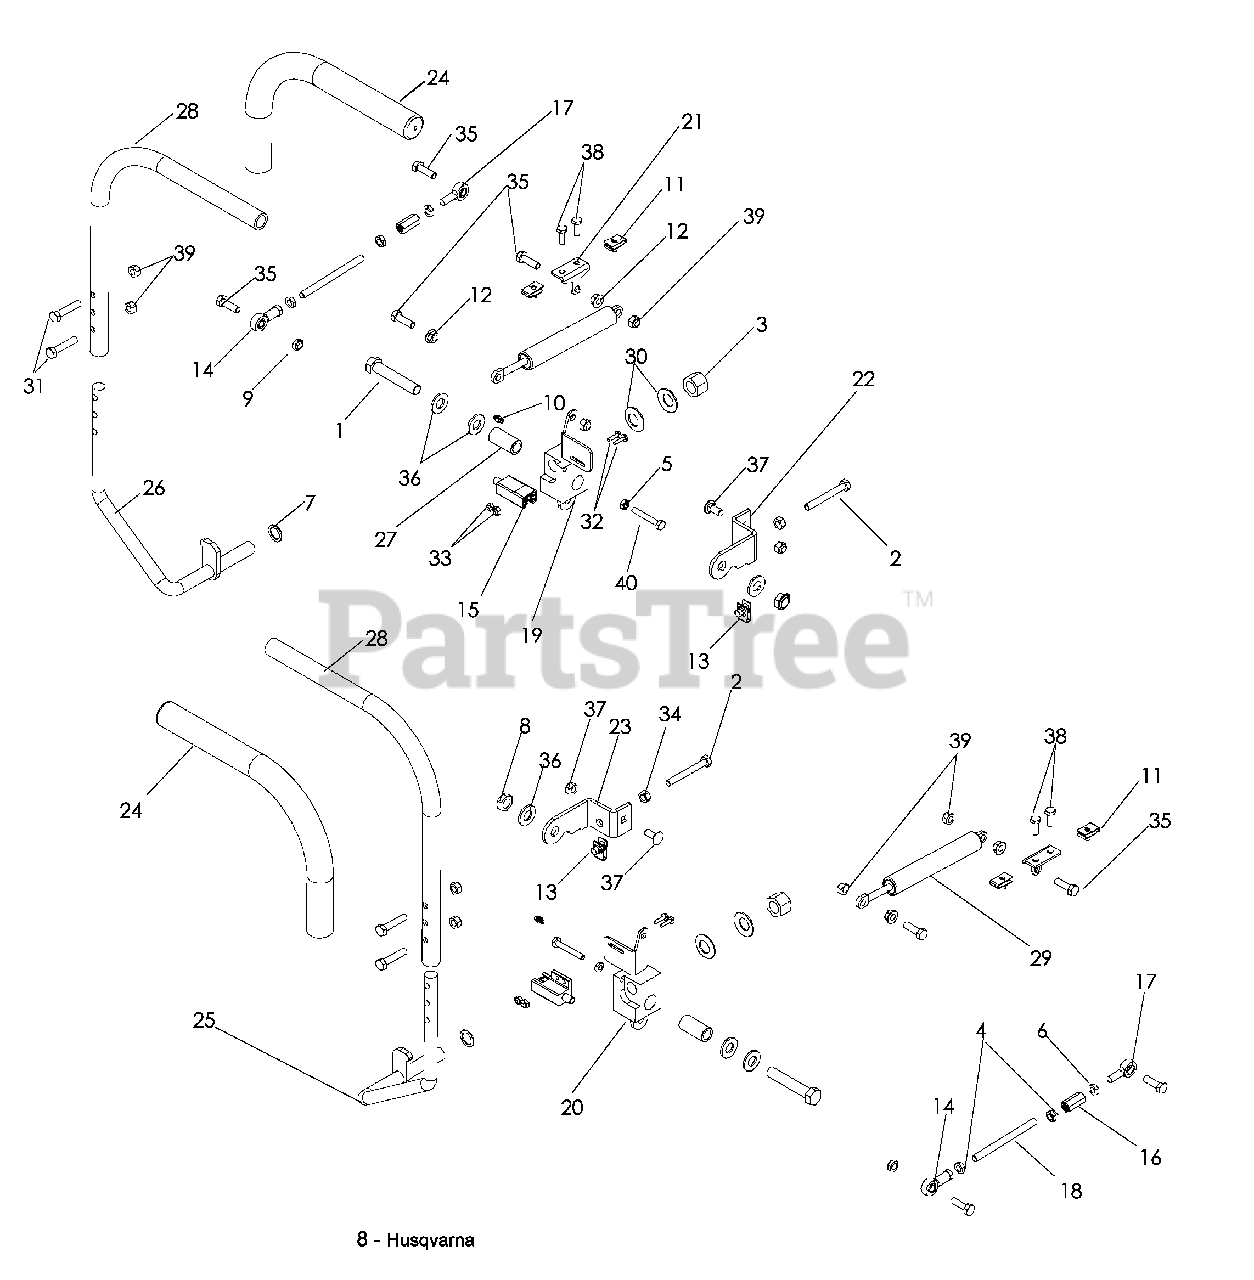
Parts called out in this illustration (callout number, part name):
1	HHB ½-13 x 2¾
2	HHB 5/16-18 x 2½
3	NUT 5/8-11 NYLOC
4	NUT 5/16-24 JAM
5	NUT ¼-20 JAM
6	NUT 5/16-24 JAM LH
7	WASHER, .626 ID x .056
8	NUT ½-13 NYLOC
9	NUT 5/16-18 NYLOC
10	GREASE ZERK
11	U TYPE RETAINER ¼
12	NUT 5/16-18 FLANGE
13	U TYPE RETAINER 5/16
14	ROD END RH
15	DECK SWITCH
16	ROD END COUPLER
17	ROD END LH
19	STEERING CONTROL RH
20	STEERING CONTROL LH
21	MOUNT, DAMPENER
22	FORWARD STOP RH
23	FORWARD STOP LH
27	BUSHING ½ ID x ¾ OD
28	LEVER, UPPER
29	DAMPENER, DUAL ACTION
30	BELLEVILLE WASHER 5/8
31	HHB 5/16-18 x 1½
32	SCR 10-24 x 5/8, PAN HD
33	NUT 10-24 NYLOC
34	NUT 5/16-18
35	HHB 5/16-18 x 1
36	WASHER ½ NARROW
37	RHSNB 5/16-18 x ¾
38	HHB ¼-20 x ¾
39	NUT 5/16-18 NYLOC
40	HHB ¼-20 x 1¾
